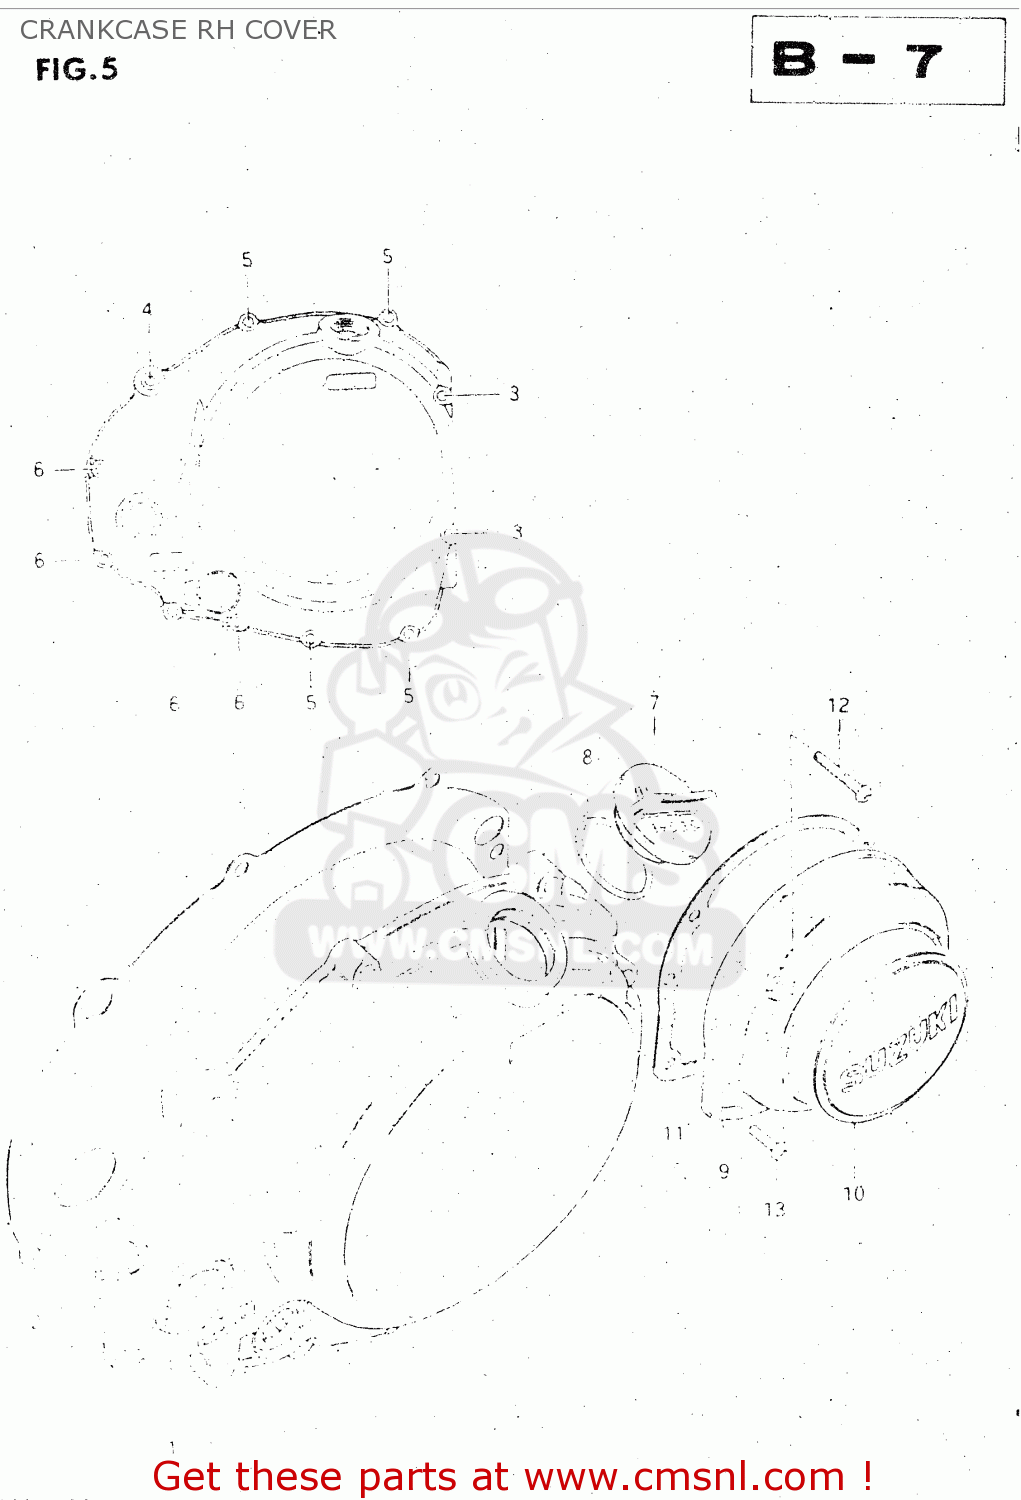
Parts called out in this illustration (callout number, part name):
1	COVER,CLUTCH
2	GASKET,CLUTCH COVER (MCA)
3	SCREW
4	SCREW (6X35)
5	SCREW
6	SCREW
7	CAP
8	O RING(D:2.2,ID:32)
9	COVER,CONTACT BREAKER
10	EMBLEM,CONTACT BREAKER COVER
11	GASKET,CONTACT BREAKER COVER (NAS)
12	SCREW
13	SCREW
